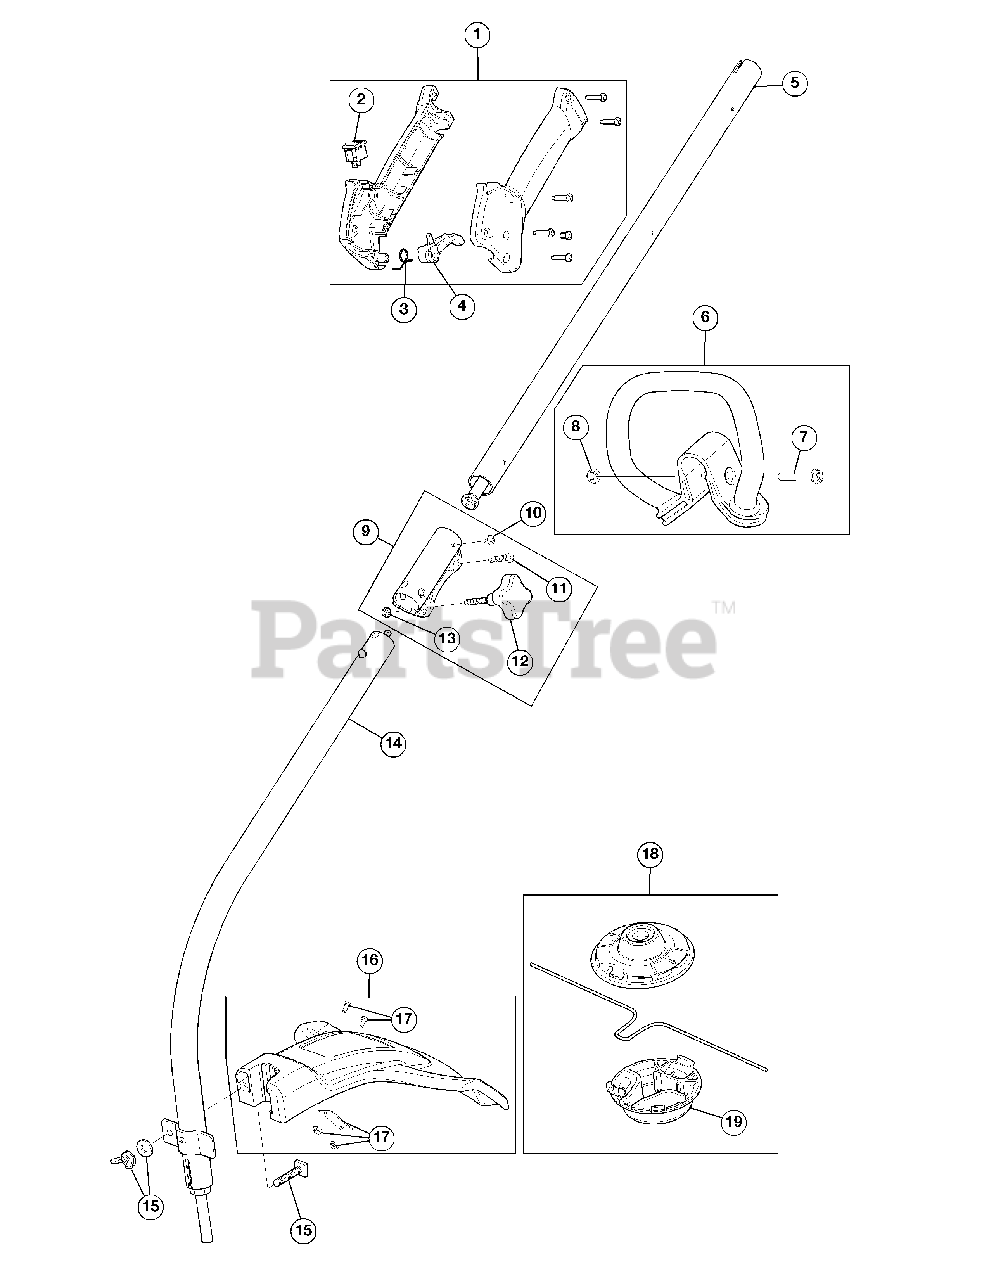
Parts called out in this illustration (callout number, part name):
1	Throttle Housing Assembly (Incl. 2 - 4)
3	Throttle Trigger Spring
4	Throttle Trigger
5	Upper Shaft Housing Assembly
6	D-Handle (Incl. 7)
7	D-Handle Bolt
8	D-Handle Nut
9	Split Boom Coupler Assembly (Incl. 10 - 13)
10	Anti-Rotation Screw
12	Adjustment Knob
13	Knob Retainer Nut
14	Lower Shaft Housing Assembly
15	Shield Mounting Hardware
16	Shield Assembly (Incl. 17)
17	Blade Assembly
18	Cutting Head Assembly (Incl. 19)
19	Glide Cap
